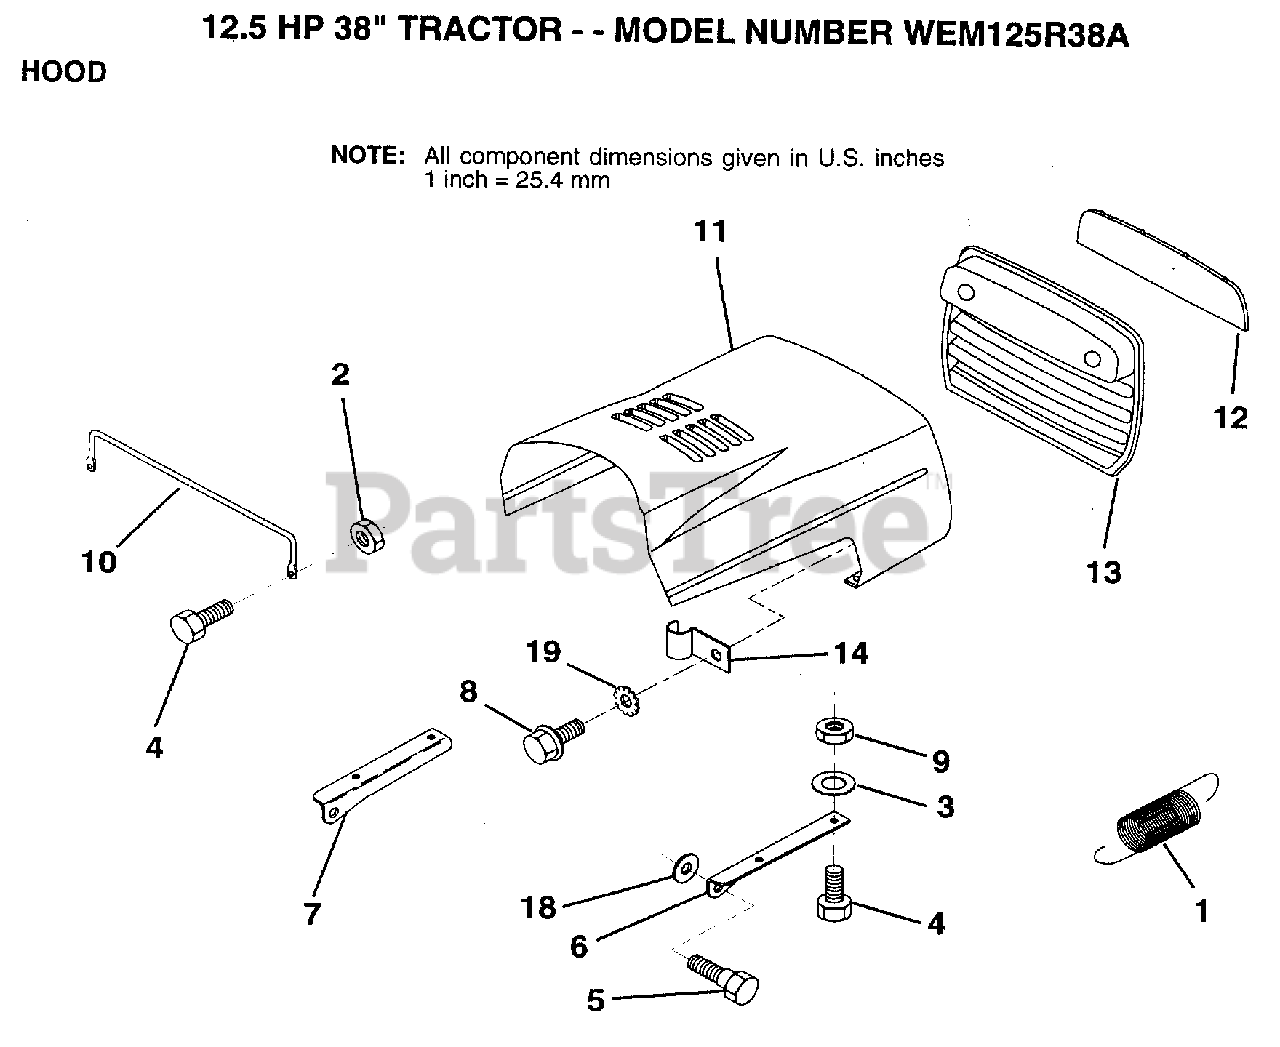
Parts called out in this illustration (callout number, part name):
1	EXT SPRING
2	NUT
3	WASHER
6	BRKT HOOD RH
7	BRKT HOOD LH
8	SCREW SLTD HXHD
9	NUT
10	"BRACE,HOOD"
11	HOOD
12	LENS
13	GRILL
14	CLIP T
18	WASHER
19	LOCKWASHER GT
